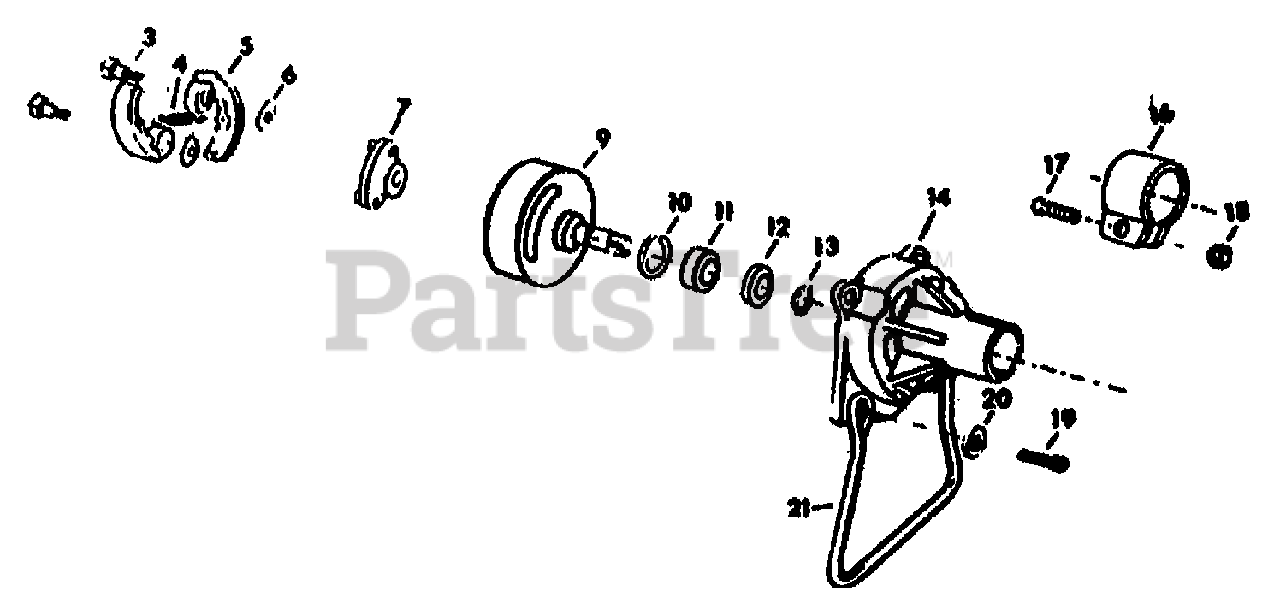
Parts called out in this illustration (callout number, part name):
3	SCREW, HEX. HD., CLUTCH
4	SPRING, GREEN, CLUTCH
5	SHOE, CLUTCH
6	WASHER, FLAT, 1/4 I.D., CLUTCH
7	ROTOR THREADED-CLUTCH
9	ASSM-DRUM & ARBOR
10	RING-RETAINING
13	RING-RETAINING
14	ASSM-CLUTCH HOUSING (INCL. 11-13)
16	CLAMP
17	SCREW, 1/4"-20X3/4", SOCKET HD. CAP
18	NUT, 1/4"-20, CLAMP
19	SCR-HXSKT 1/4-20X.75
20	WASHER-MOTOR LEG
21	LEG-MOTOR
